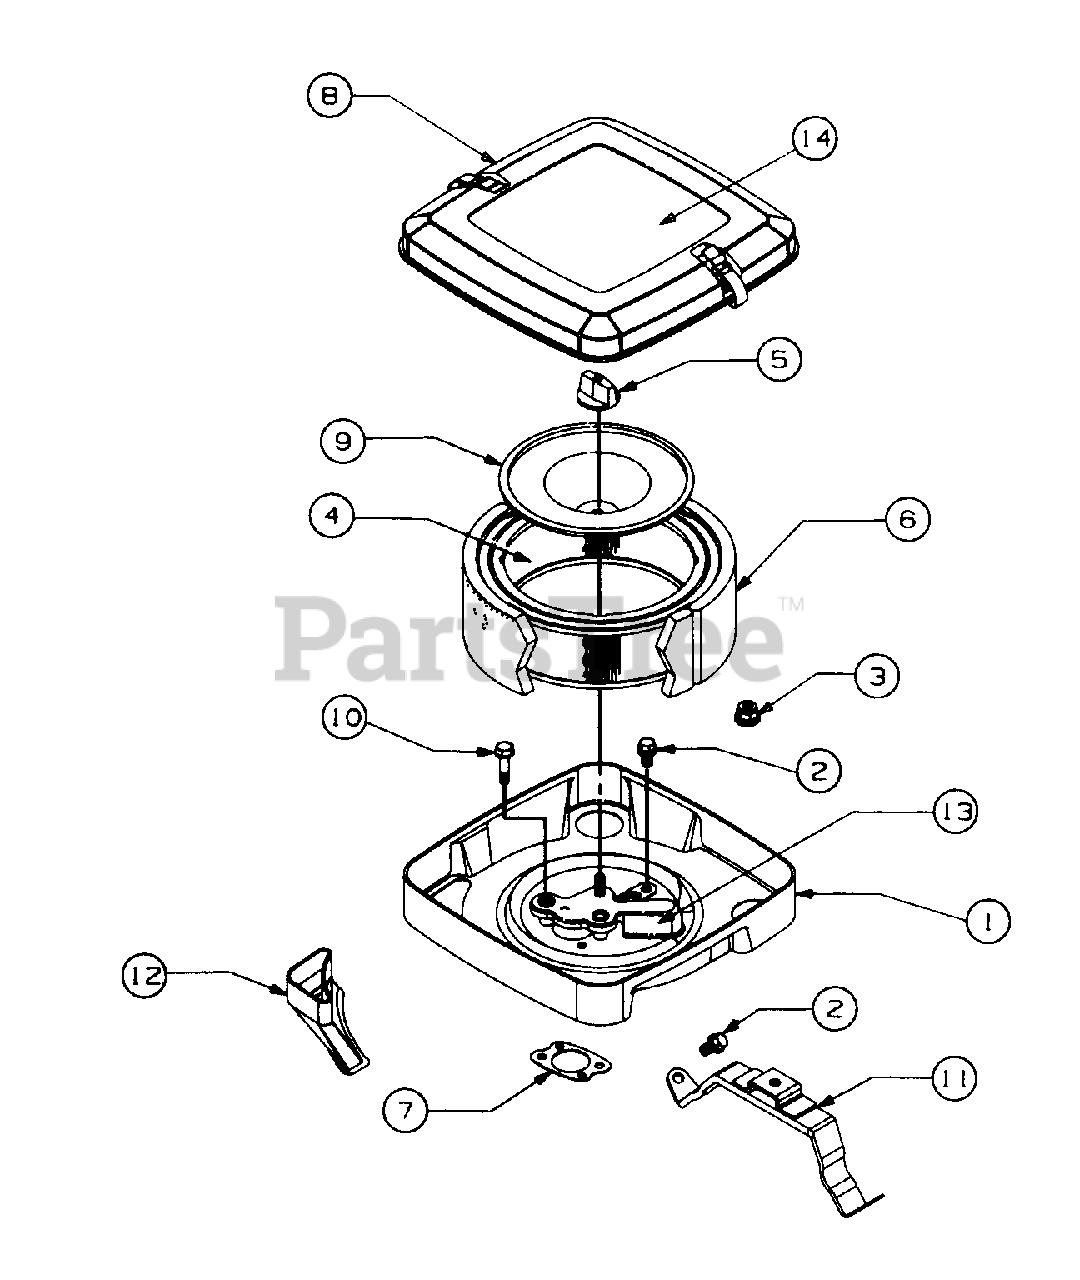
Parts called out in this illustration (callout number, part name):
1	Base, Air Cleaner
2	Screw, Sem
4	Cartridge, Air Filter
5	Knob, Air Cleaner
6	Element, Pre-Cleaner
7	Gasket, Air Cleaner
8	Cover, AirCleaner
9	Plate, Cartridge
10	Screw, Sem
11	Bracket, AirCleaner
12	Tube, Air Inlet
13	Shield, Carburetor Air Cleaner
14	Label, V-Twin Engine
